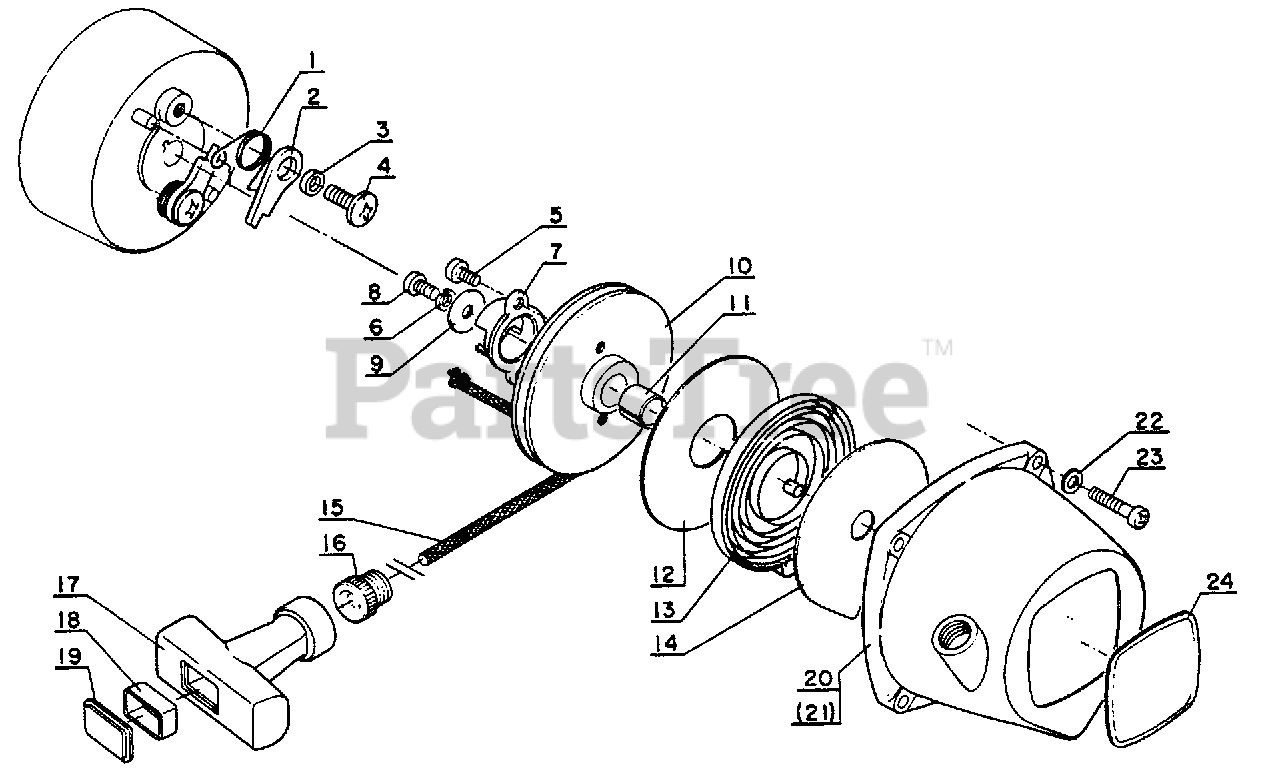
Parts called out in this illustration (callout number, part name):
1	SPRING, RETURN
2	PAWL, STARTER
4	SCREW
5	SCREW - 4X8
6	LOCKWASHER - 4
7	CATCHER, PAWL
8	SCREW - 4X6
10	REEL, ROPE
12	PLATE, STARTER
13	SPRING, REWIND
14	PLATE, STARTER
15	ROPE, STARTER - 3.5X850
16	GUIDE, ROPE
17	GRIP, STARTER
18	RING, RETAINING
20	CASE, STARTER
22	WASHER - 4
23	SCREW - 4X20
24	LABEL - KIORITZ
